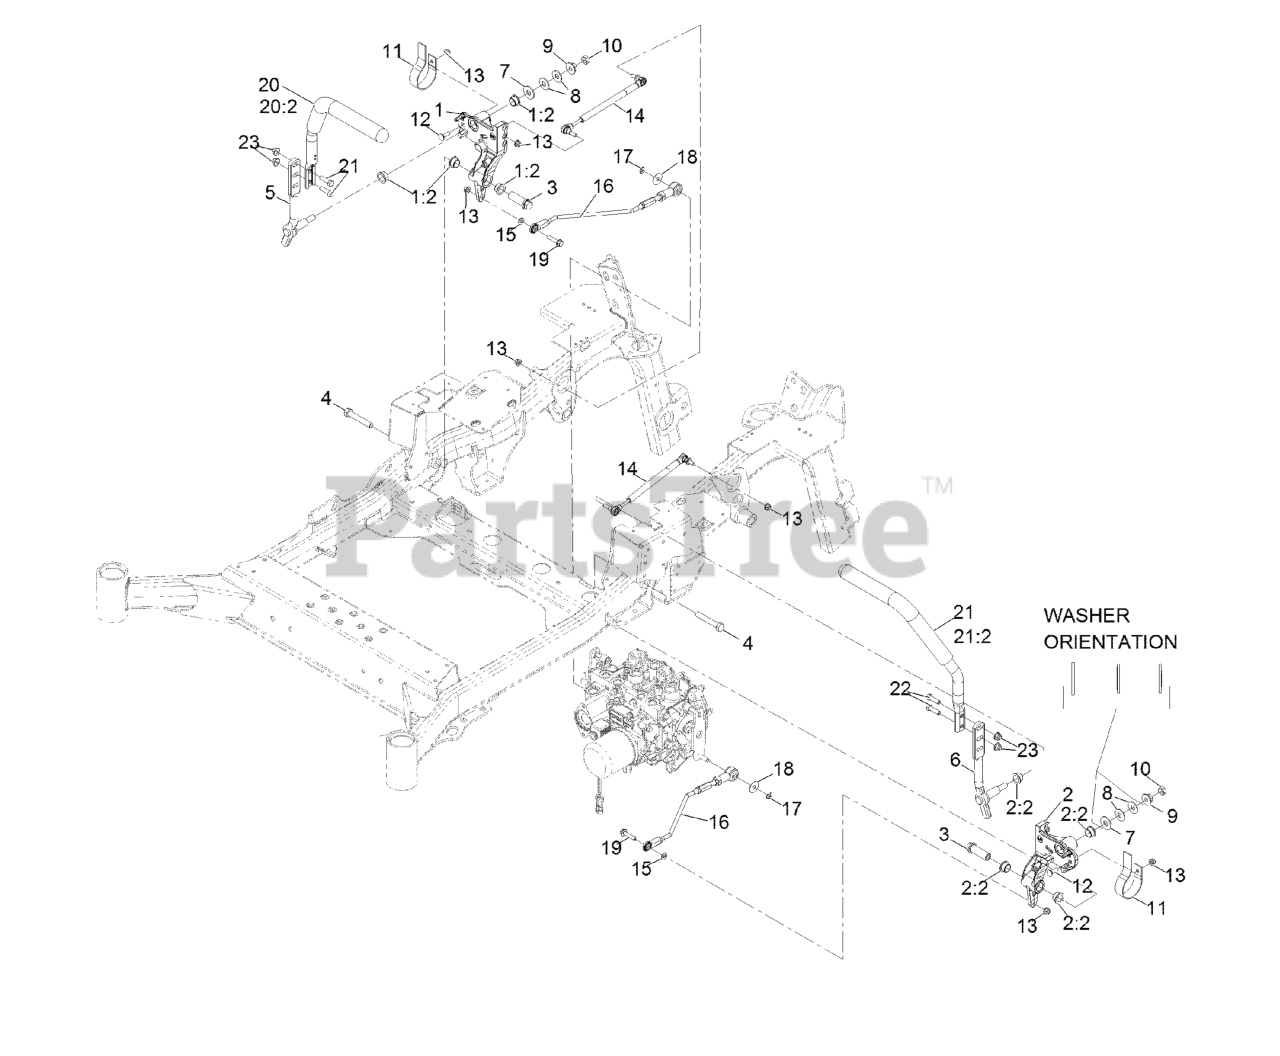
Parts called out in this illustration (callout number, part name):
1	RH MOTION CONTROL AND BUSHING ASM
1:2	BUSHING-FLANGE
2	LH MOTION CONTROL AND BUSHING ASM
2:2	BUSHING-FLANGE
3	HUB-THREADED
4	SCREW-HH
5	LEVER-CONTROL MOTION, RH
6	LEVER-CONTROL MOTION, LH
7	WASHER-FLAT
8	WASHER-SPRING
10	NUT-JAM
11	SPRING-LEAF
12	BOLT-CARR
13	NUT-HF, NI
14	DAMPER-CONTROL, MOTION
15	WASHER-PLAIN
16	FRONT LINKAGE ROD ASM
17	RING-RETAINING
18	WASHER-PLAIN
19	SCREW-HHF
20	RH STEERING HANDLE ASM
20:2	GRIP-LEVER, CONTROL
21	LH STEERING HANDLE ASM
21:2	GRIP-LEVER, CONTROL
22	SCREW-HH
23	NUT-HF, NI
